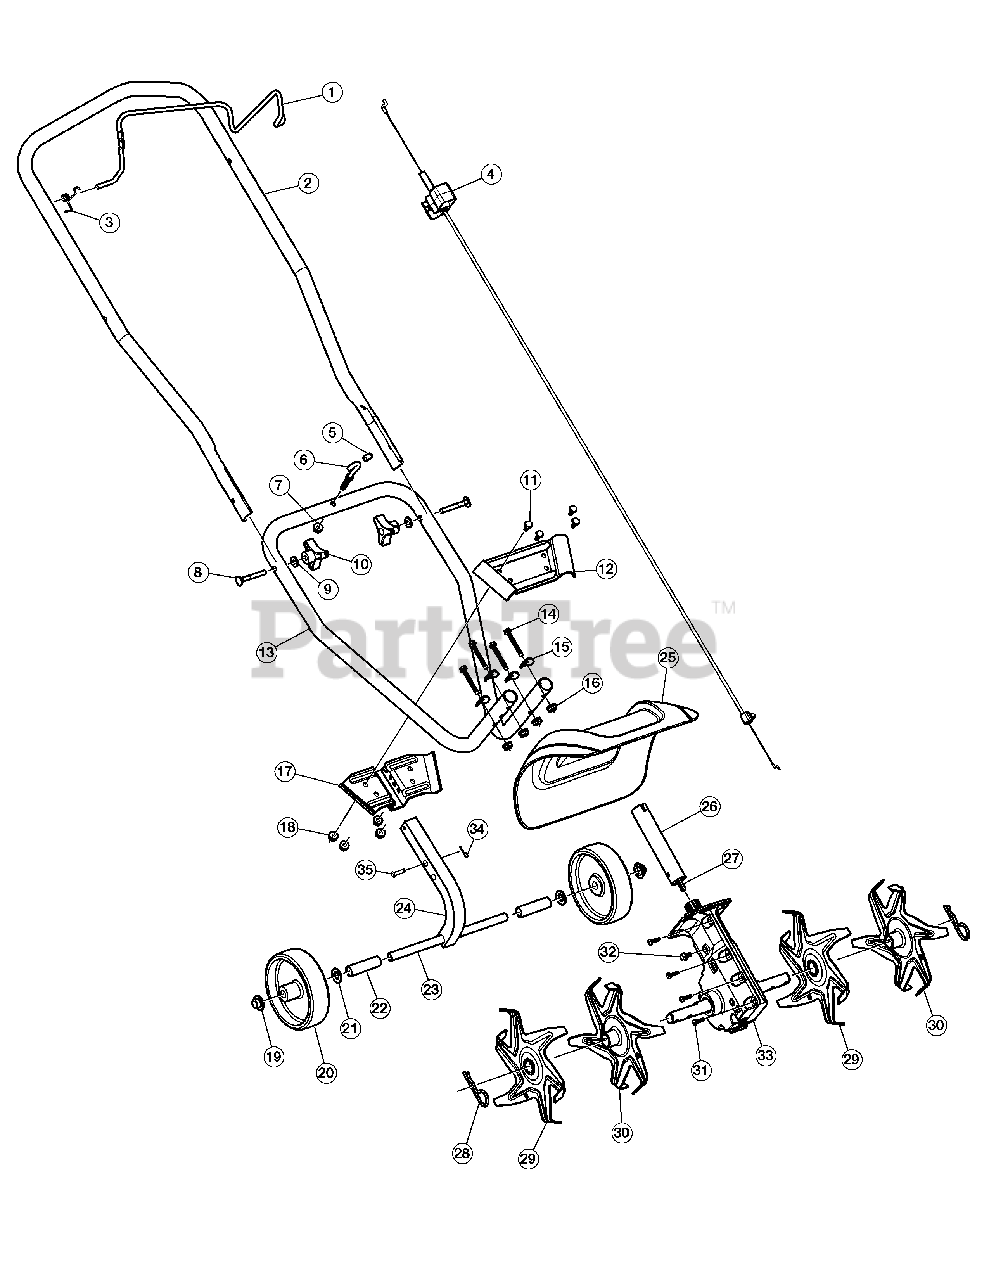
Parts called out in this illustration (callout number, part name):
1	Throttle
2	Handle
3	Spring
4	Throttle Cable
6	Eyelet Bolt
9	Washer
11	Screw
12	Bracket, Upper
13	Handle
14	Bolt
15	Washer
17	Bracket, Lower
20	Wheel (Incl. 19)
22	Spacer
24	Tube, Square
25	Shield
26	Tube (Incl. 27)
27	Flex Shaft
29	Tine (Left Inner, Right Outer)
30	Tine (Left Outer, Right Inner)
32	Screw
33	Gearbox (Incl. 31)
34	Cotter Pin
35	Clevis Pin
